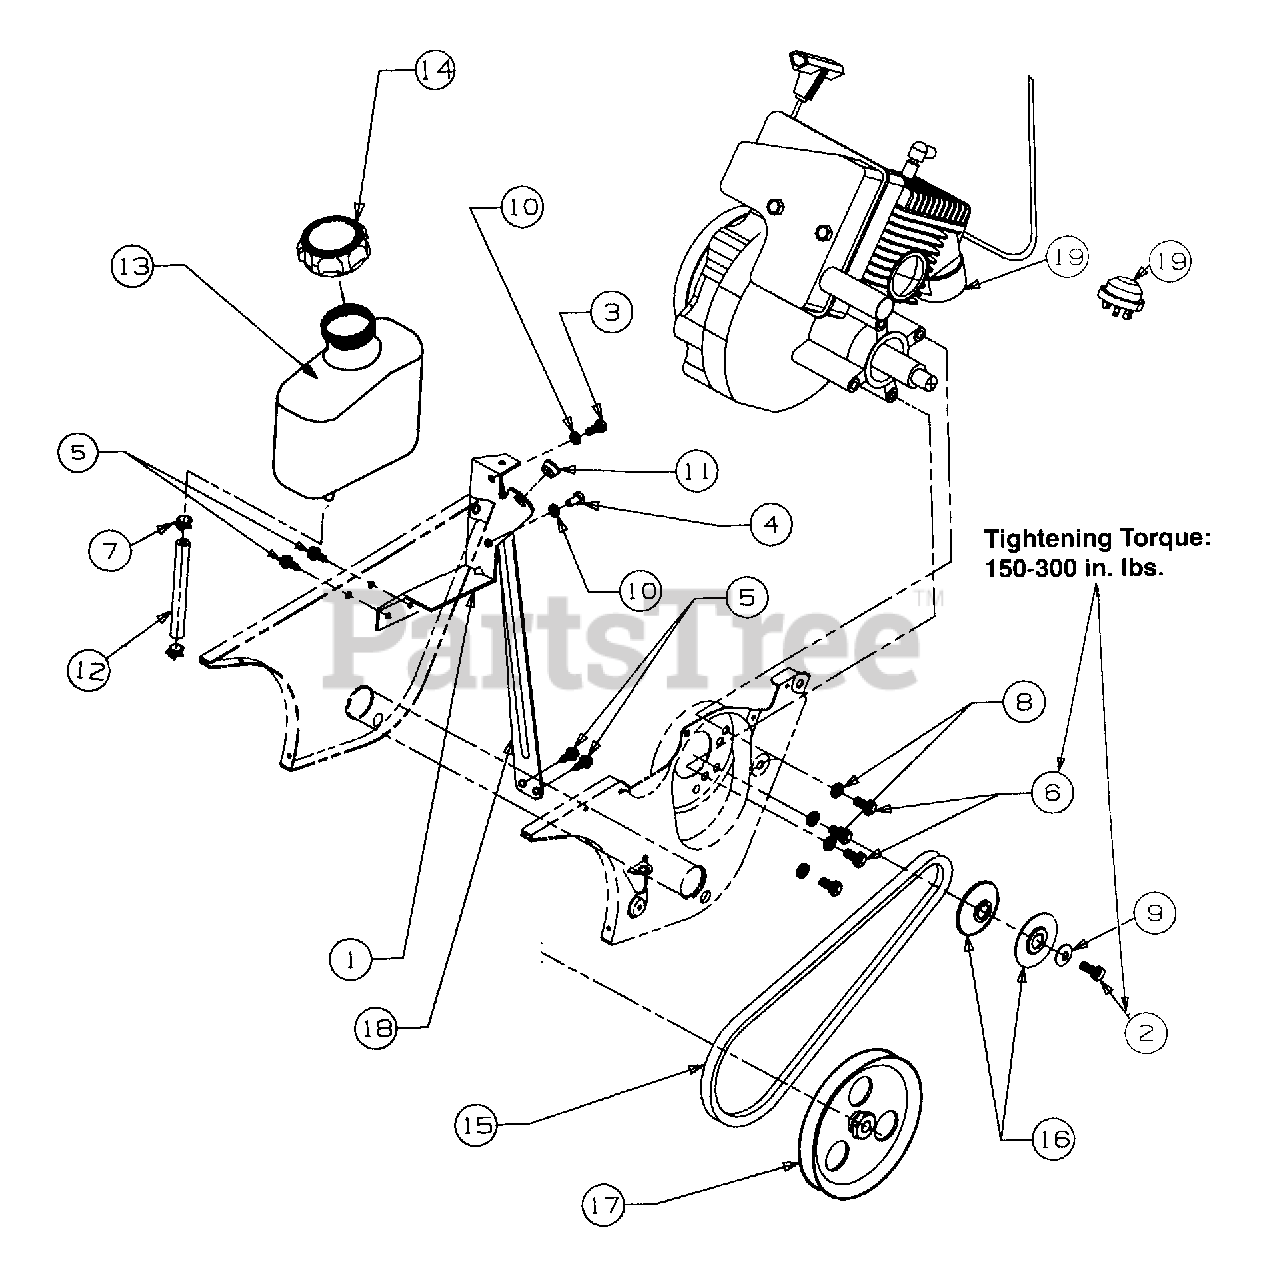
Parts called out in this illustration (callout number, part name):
1	Bracket - Support Gas Tank
2	Screw - Hex Cap
3	Screw - Hex Cap
4	Screw - Hex
5	Screw - Washer
6	Screw - Hex Cap
7	Clamp - Hose
8	Washer - Lock
9	Washer - Bell
10	Washer - Lock
11	Bushing - Plastic
12	Hose - Fuel Line 16"
13	Tank - Fuel 2 Qt.
14	Cap - Fuel
15	V-Belt
16	V-Pulley Half
17	Pulley
